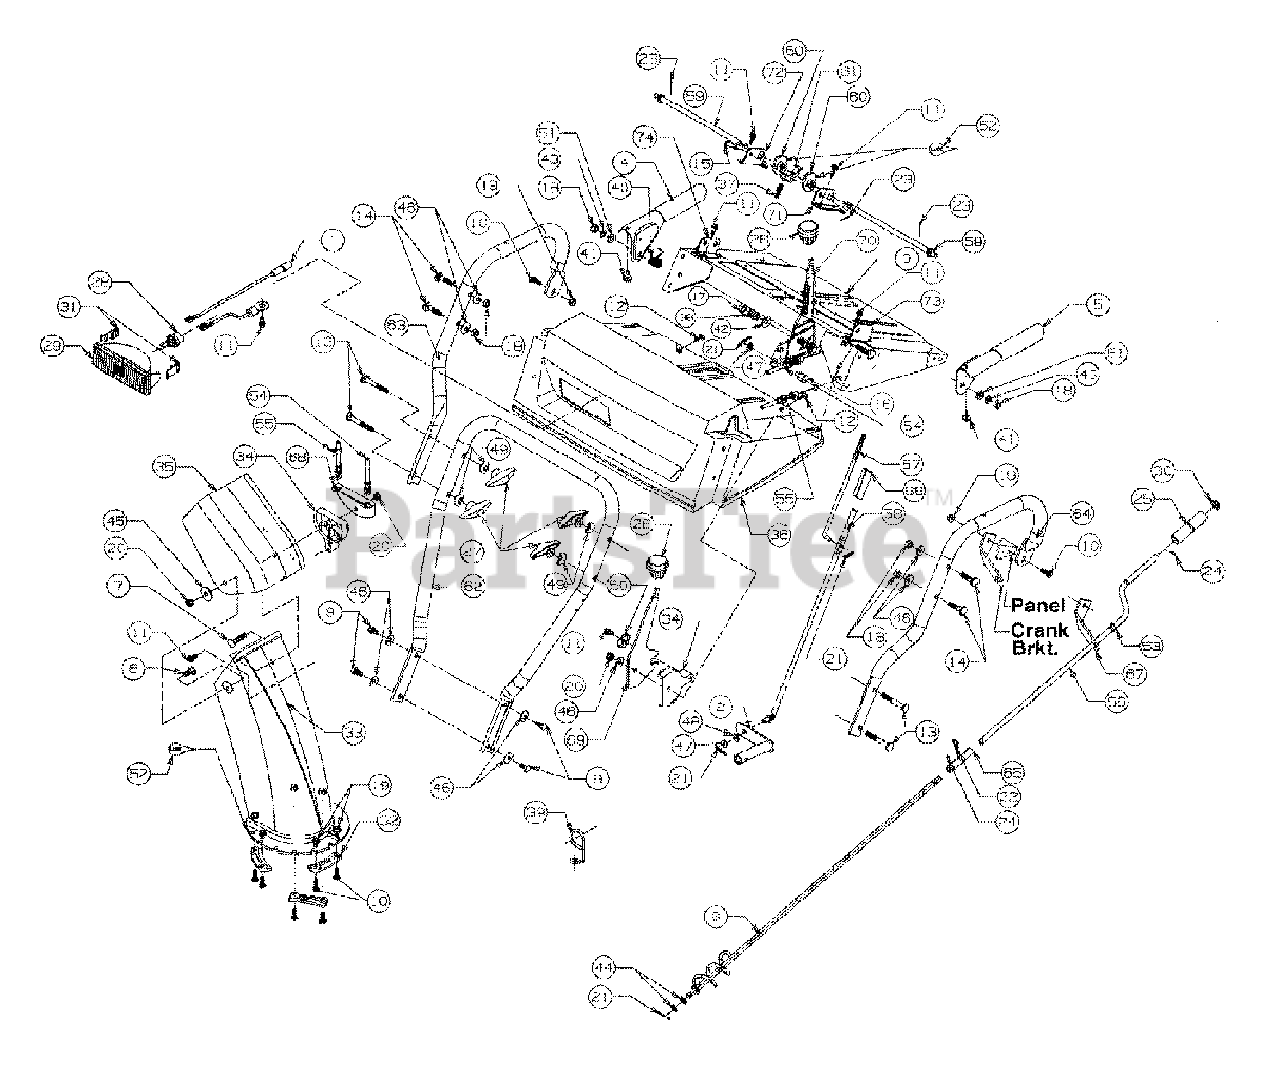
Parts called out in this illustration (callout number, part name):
1	Harness-Light
2	Arm-Shift
5	Handle-Engagement - L.H.
6	Crank-Chute
7	Bolt-Carriage
8	Bolt-Carriage
9	Screw-Hex
10	Screw-Hex
11	Screw-Washer Head-Hex
12	Screw-Hex
13	Bolt-Carriage
14	Bolt-Carriage
15	Pin-Clevis
16	Ferrule
17	Nut-Hex Lock
18	Nut-Hex
19	Nut-Hex Lock
20	Nut-Hex Lock
21	Pin-Cotter Internal
22	Pin-Cotter
24	Pin-Roll
25	Knob-Chute Crank
26	Knob-Shift
27	Knob-Wing Nut
29	Housing-Lamp
30	Cap-Push
31	Clip-Retaining
32	Keeper-Chute
33	Chute-Lower
34	Guide-Cable
35	Chute-Upper
36	Panel-Handle
37	Spring
38	Spring
39	Wire-Control
40	Spring
41	Bumper
42	Washer-Bell
43	Washer-Lock
44	Washer-Flat
45	Washer
46	Washer-Bell
47	Washer-Flat
48	Washer-Lock
49	Washer-Saddle
50	Washer
51	Washer
52	Lubricant
53	Bushing-Plastic
54	Cable-Chute Control
55	Cable-Chute Control
56	Crank-Chute
57	Rod-Shift Upper
58	Rod-Shift Lower
59	Rod-Cam
60	Cam-Handle Lock
61	Pawl-Handle Lock
62	Handle-Lower
63	Handle - R.H.
64	Handle - L.H.
65	Spacer
66	Connector
69	Handle-Chute Tilt
70	Handle-Shift
71	Bracket-Handle Support - L.H.
72	Bracket-Handle Support - R.H.
74	Bracket-Handle Support - R.H.
